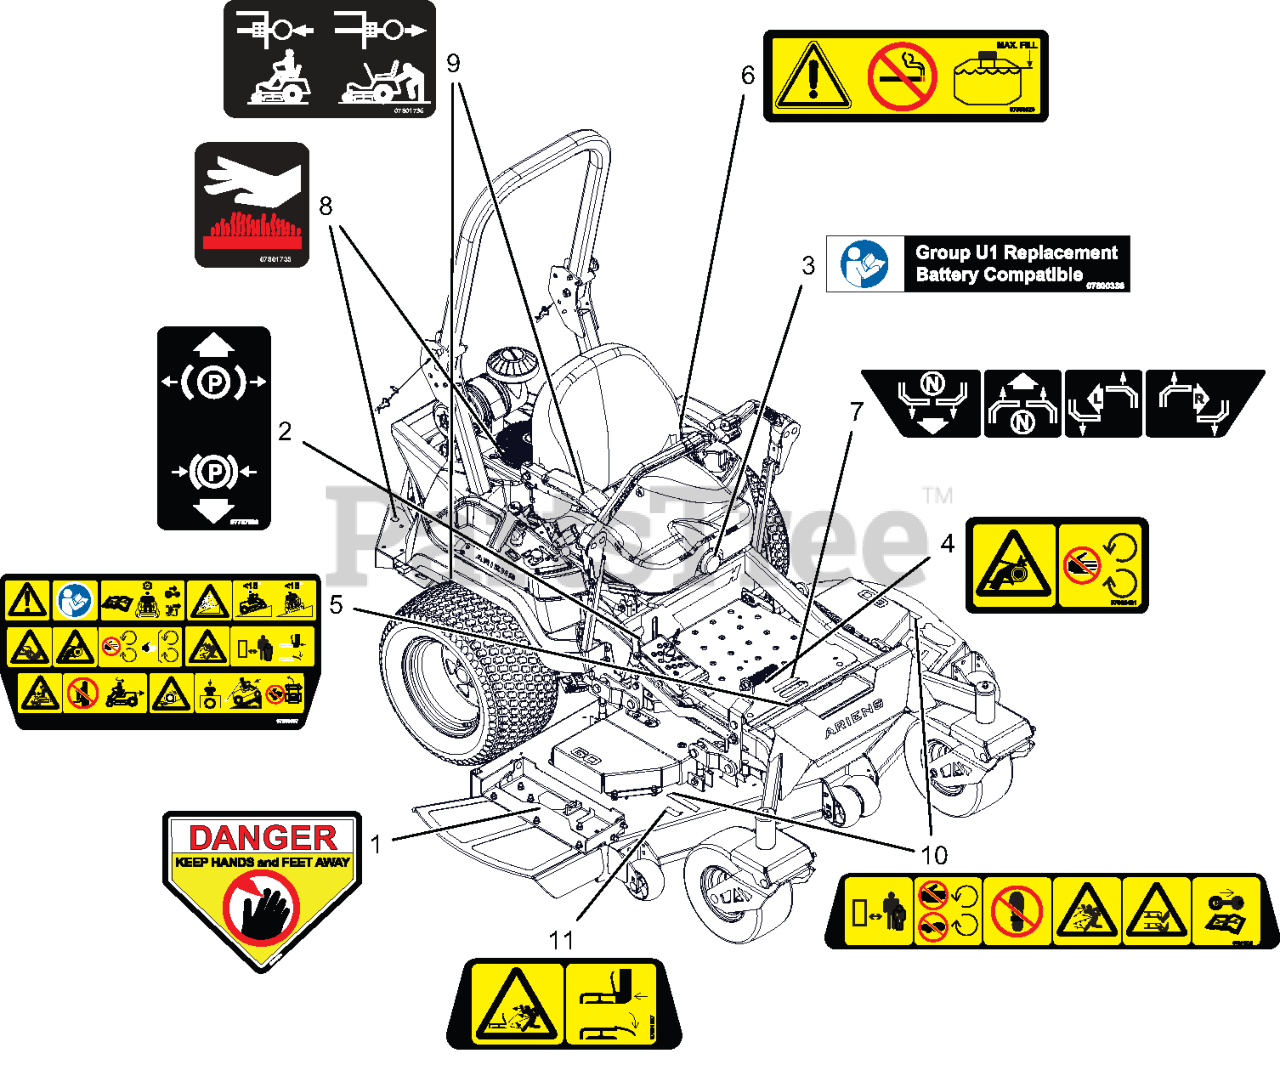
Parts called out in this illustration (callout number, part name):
1	DECAL, DANGER
2	DECAL, PARKING BRAKE LEVER
3	DECAL, U1 BATTERY REPLACEMENT
4	DECAL, SAFETY - GUARDING
5	DECAL, MAIN SAFETY
6	DECAL, FUEL WARNING
7	DECAL, INSTRUCTION - STEERING
8	DECAL- HOT SURFACE
9	DECAL- TRANSAXLE DISCONNECT
10	DECAL- SAFETY - MOWER DECK
11	DECAL- SAFETY - DECK GUARDING
